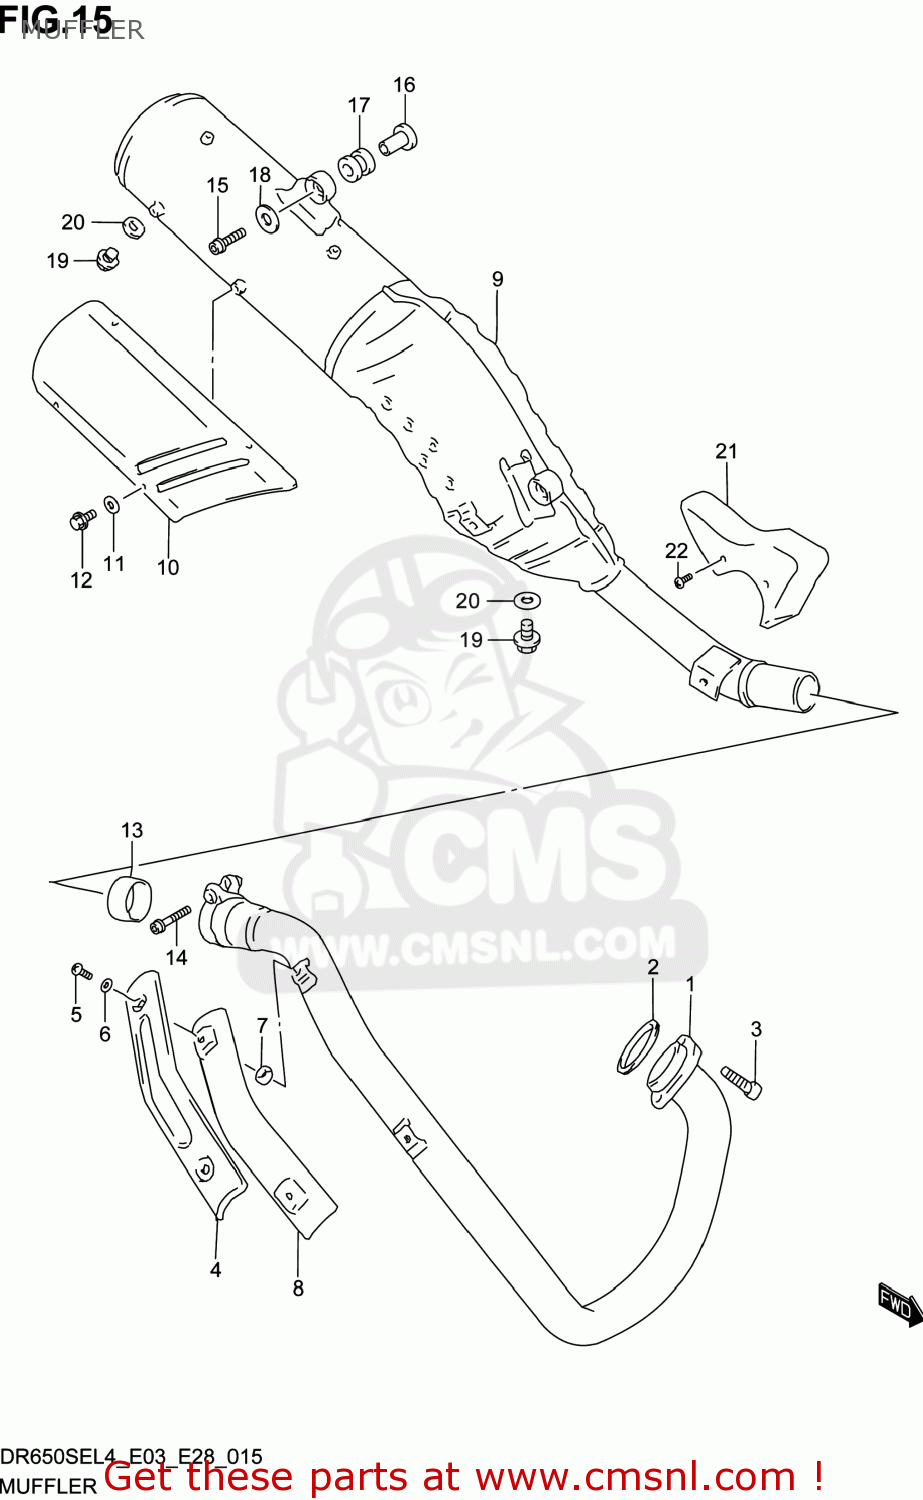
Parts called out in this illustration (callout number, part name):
1	PIPE,EXHAUST
2	GASKET,EXHAUST PIPE (NAS)
3	BOLT
4	COVER,EXHAUST PIPE
5	SCREW(6X12)
6	WASHER(6.5X13X1.0)
7	GASKET(6X16X1.4) (NAS)
8	COVER,EXHAUST PIPE INNER
9	BODY,MUFFLER
10	COVER,MUFFLER
11	WASHER(6.5X13X1.0)
12	SCREW(6X10)
13	CONNECTOR,MUFFLER
14	BOLT
15	BOLT(8X30)
16	SPACER(8.6X12X17.5)
17	CUSHION
18	WASHER(8.5X28X1.6)
19	PLUG(12X9)
20	GASKET(12.1X16.2X3.7) (NAS)
21	COVER,CONNECTOR CLAMP
22	SCREW(6X10)
